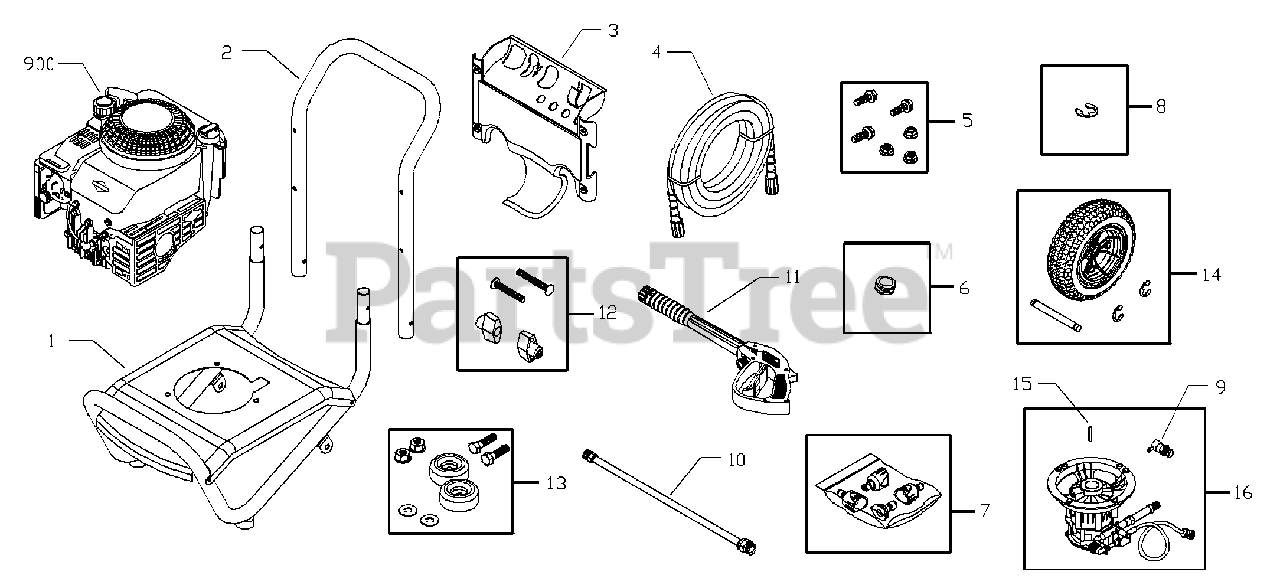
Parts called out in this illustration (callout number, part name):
3	ASSY, Billboard w/ Clips
4	HOSE
5	KIT, Pump Mounting Hardware
7	KIT, Nozzle, QC
8	E-RING
9	VALVE,Thermal Relief
10	ASSY, Extension
11	GUN
12	KIT, Handle Connector
13	KIT,Vibration Mount
16	ASSY, Pump
900	ENGINE
